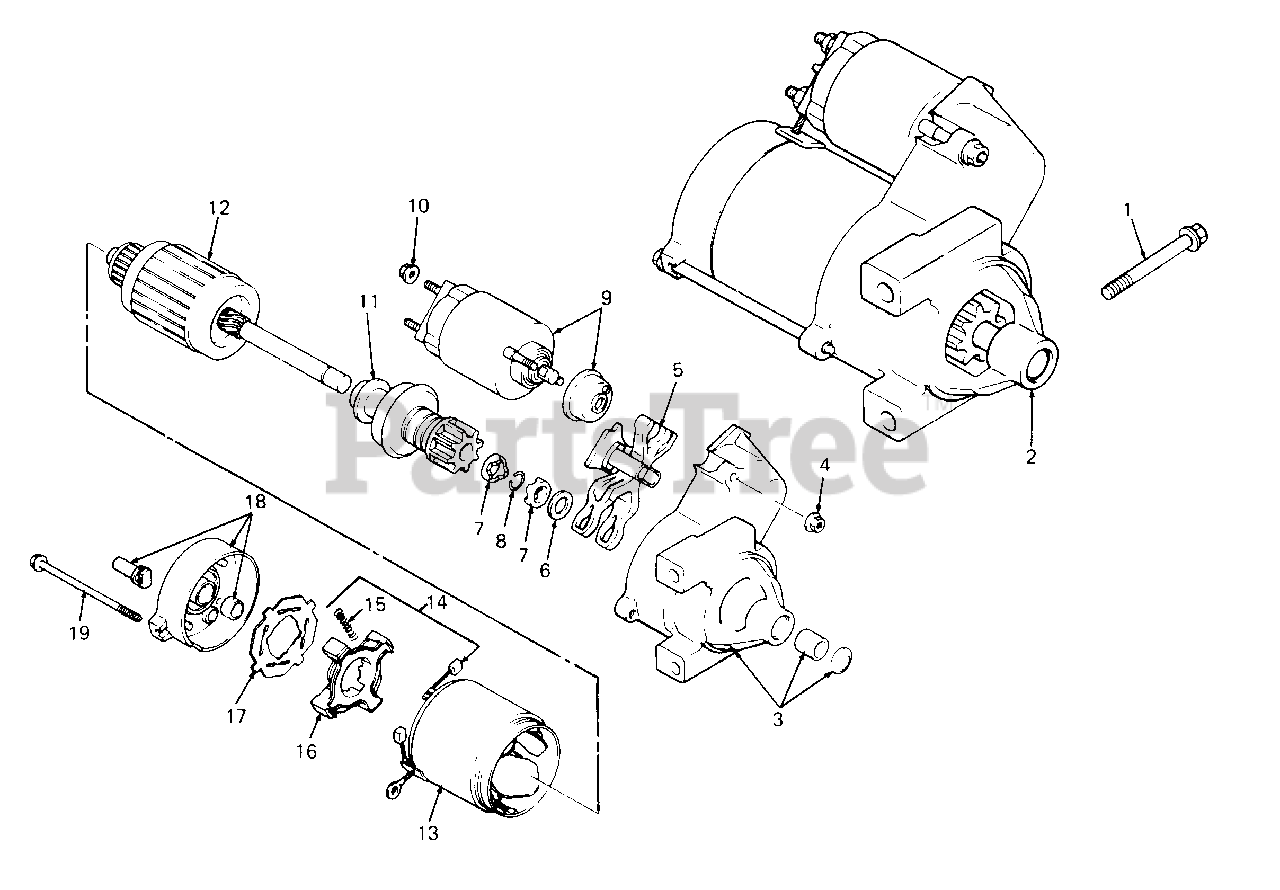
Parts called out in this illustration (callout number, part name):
1	Screw, M8 X 1.25 X 80.6
2	Starter Assy, Solenoid Shift (Nippon Denso)
3	Cap, Drive End
4	Nut, Starter
5	Lever, Starter Drive
6	Washer, Thrust
7	Nut, Stop Collar
8	Ring, Retainer
11	Drive, Pinion
14	Kit, Brush
15	Spring, Brush
16	Holder, Brush
18	Cap, Commutator End
